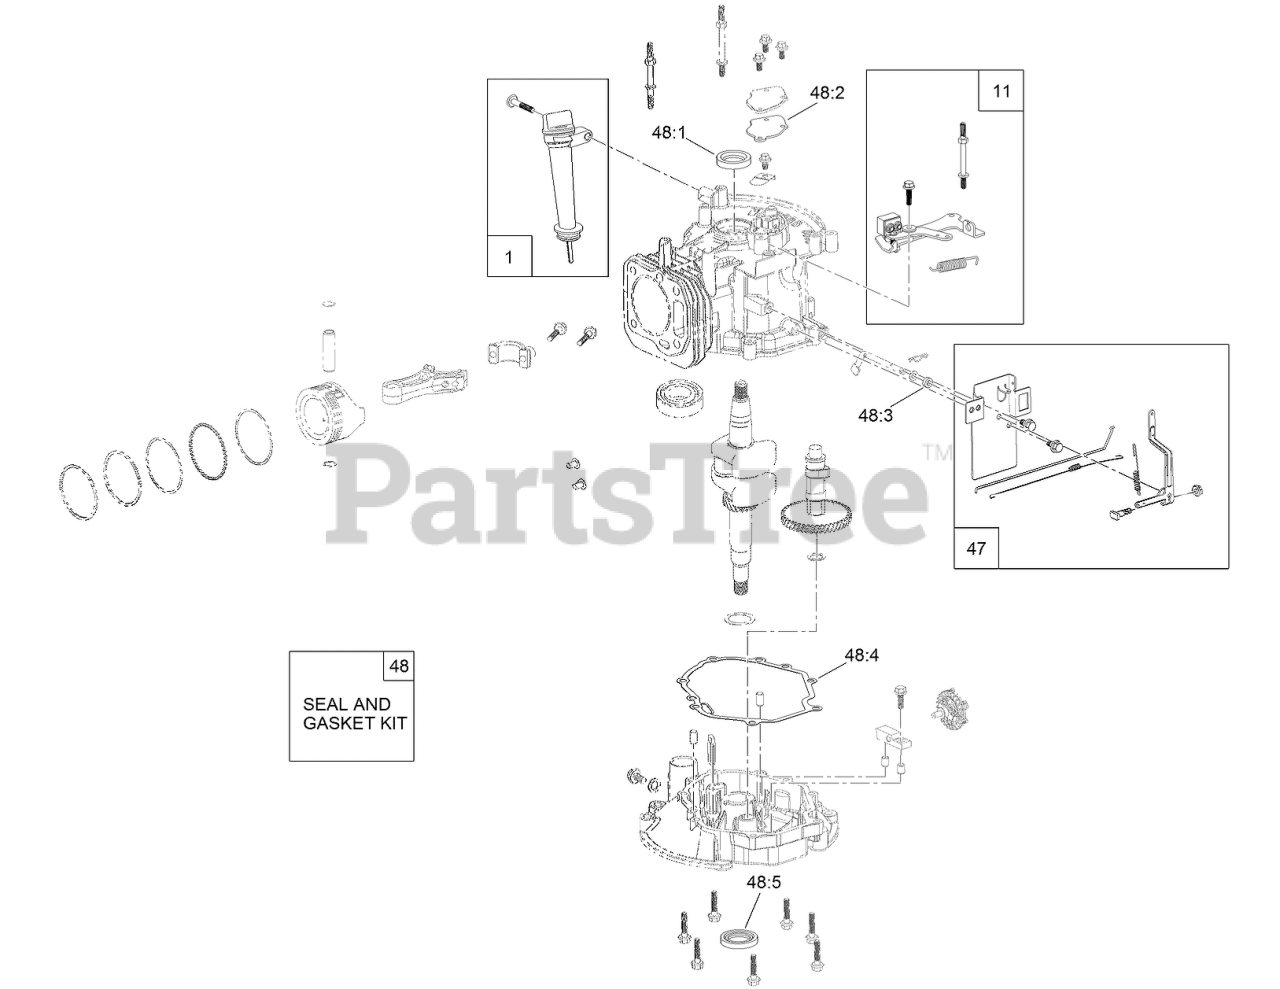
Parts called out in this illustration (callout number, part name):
1	DIPSTICK AND FILL TUBE KIT
11	BRAKE ASM RECOIL KIT
47	GOVERNOR ARM KIT
48	SEAL AND GASKET KIT
48:1	SEAL-OIL
48:2	GASKET-BREATHER
48:3	SEAL-OIL
48:4	GASKET-COVER, CASE
48:5	SEAL-OIL
